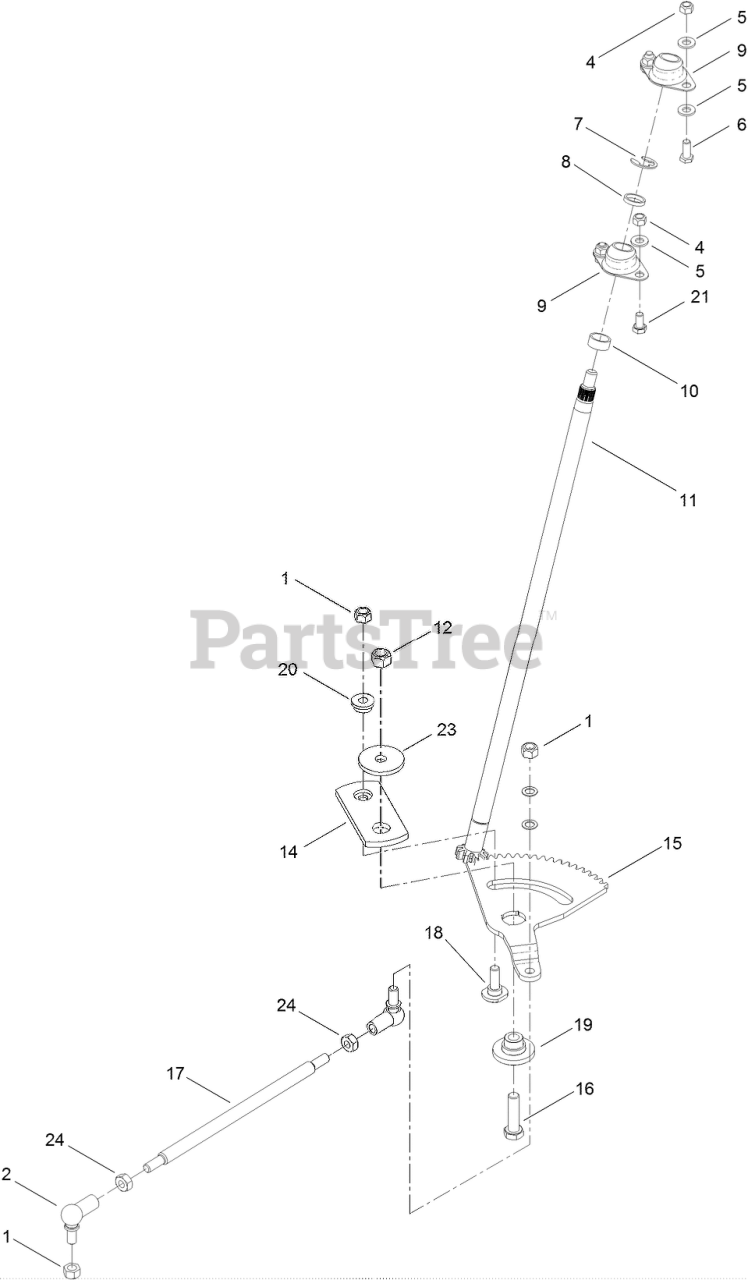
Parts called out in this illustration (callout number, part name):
1	NUT-LOCK, NI
2	JOINT-BALL, ANGLE
4	NUT-LOCK, NI
5	WASHER-PLAIN
6	SCREW-HH
7	CLIP-SPRING
8	SPACER-UPPER
9	BEARING-SPHERICAL
10	SPACER-LOWER
11	Shaft-Steering
12	NUT-LOCK
14	Plate-Steering
15	GEAR-SECTOR
16	SCREW-HH
17	LINK-DRAG
18	Bolt-Shoulder
19	Pivot-Steering
20	Bushing
21	SCREW-HH
23	WASHER
24	NUT
